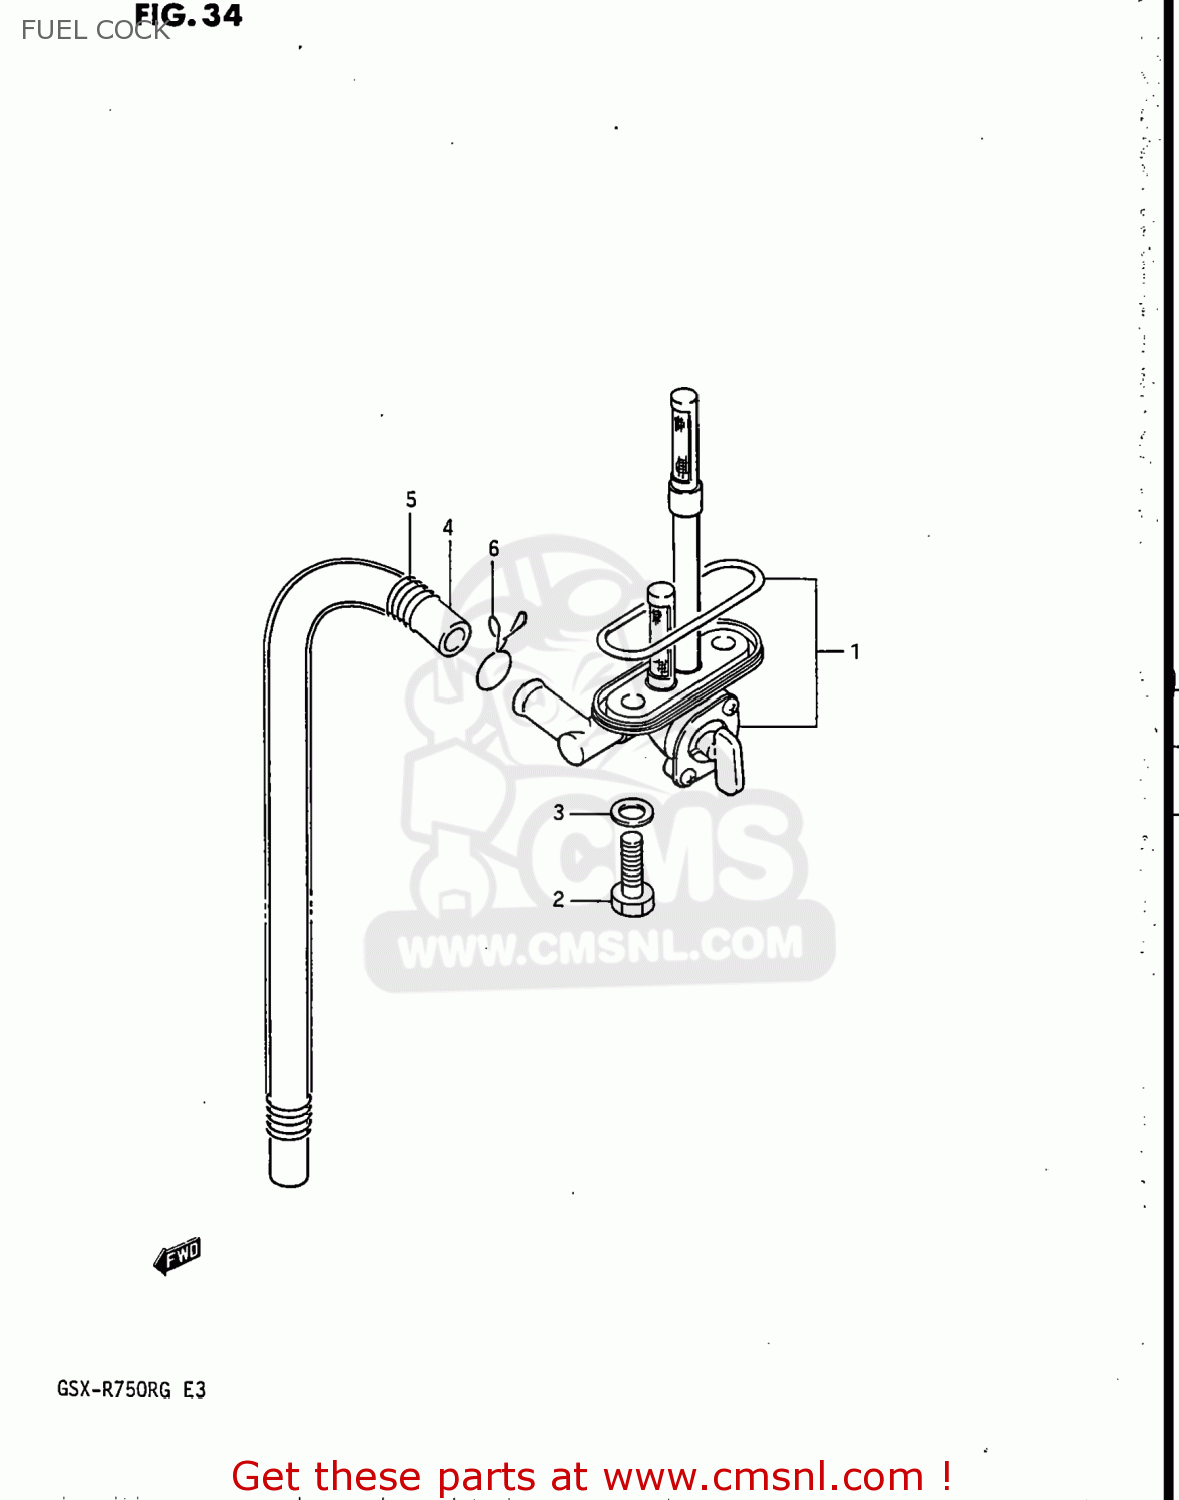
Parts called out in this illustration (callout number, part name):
1	COCK ASSEMBLY,FUEL
2	BOLT(6X20)
3	GASKET
4	HOSE
5	SPRING
6	(CA) CLIP
